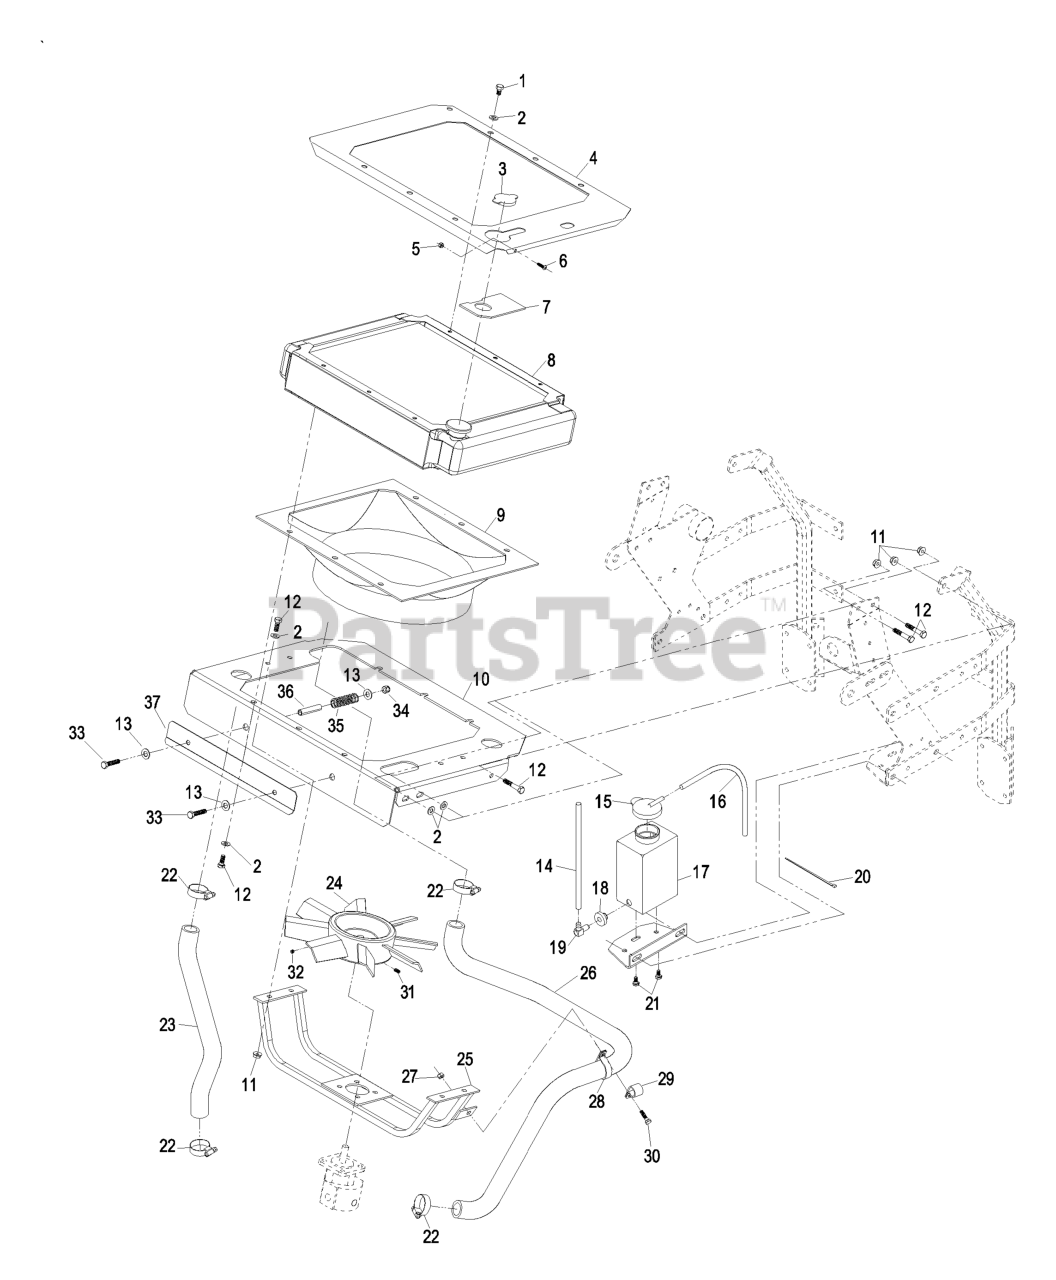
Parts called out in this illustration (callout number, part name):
1	SCREW-HH
2	WASHER-PLAIN
3	CAP-RADIATOR
4	ASM,RAD. TOP PLATE W/DECA
5	NUT-LOCK, NI
6	SCREW-HEAD, TRUSS
7	SHIELD-FILL NECK, RADIATO
9	SHROUD-COOLING, ENGINE
12	SCREW-HH
13	WASHER-FLAT
15	CAP-TANK, OVERFLOW
17	TANK-OVERFLOW
20	TIE-CABLE
21	SCREW-HH
23	HOSE-OUTLET, ENGINE
24	FAN
25	MOUNT-MOTOR, FAN
26	HOSE-INLET, ENGINE
27	NUT-LOCK, NI
28	CLIP-LOOM
29	CLIP-LOOM
30	SCREW-HH
31	SCREW-SET
32	Setscrew,1/4-20 X 1/4
33	SCREW-HH
34	NUT-LOCK, NI
35	SPRING-INDICATOR, REVERSE
37	BRACKET-DEFLECTOR, AIR
